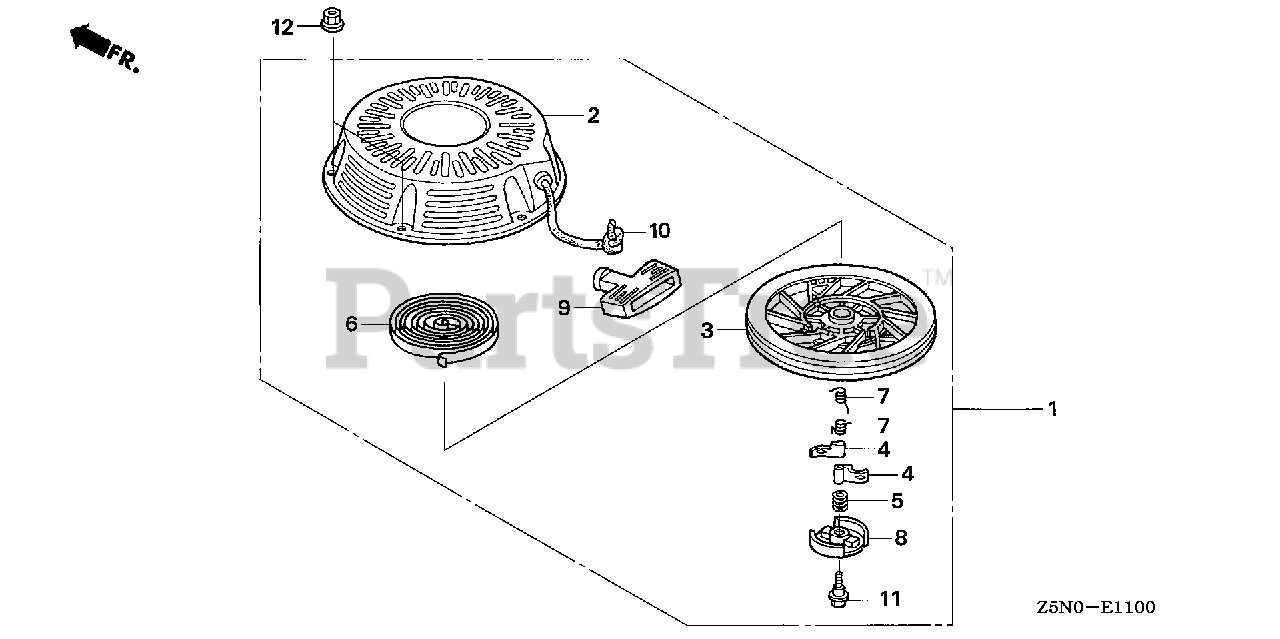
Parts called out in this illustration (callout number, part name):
1	STARTER ASSY., RECOIL *NH1* (BLACK)
1	STARTER ASSY., RECOIL *R280* (POWER RED)
2	CASE, RECOIL STARTER *NH1* (BLACK)
2	CASE, RECOIL STARTER *R280* (POWER RED)
3	PULLEY, RECOIL STARTER
4	RATCHET, STARTER
5	SPRING, FRICTION
6	SPRING, STARTER RETURN
7	SPRING, RATCHET
8	RETAINER, SPRING
9	GRIP, STARTER
10	ROPE, RECOIL STARTER
11	SCREW, CENTER
12	NUT, FLANGE (6MM)
